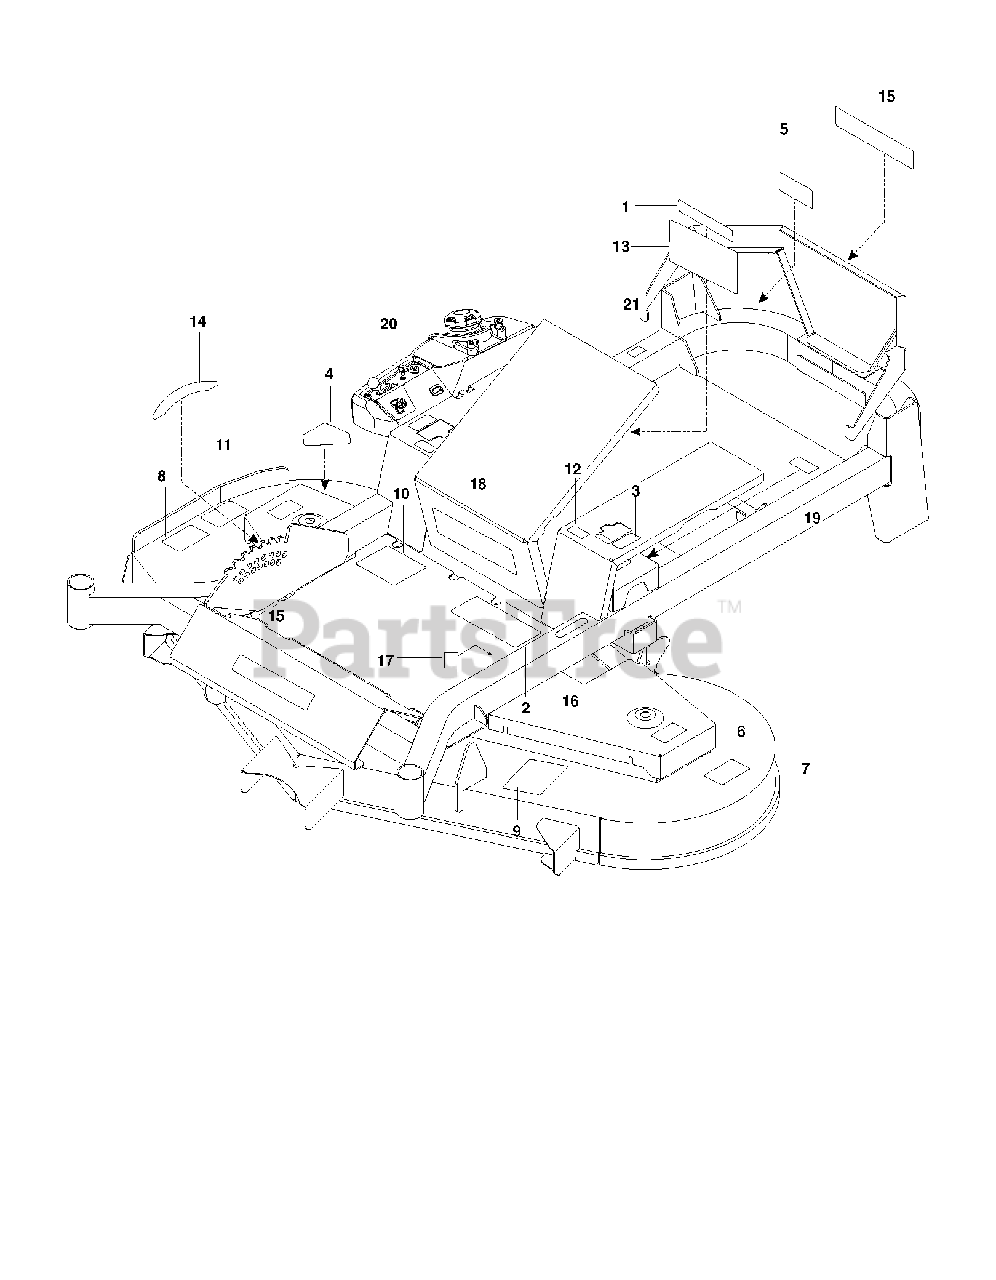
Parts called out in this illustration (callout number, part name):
2	DECAL, WARNING
3	DECAL, MOTION CONTROL
4	DECAL, CPSC
5	DECAL, BELT DRIVE
6	DECAL, NO STEP
8	DECAL, EURO SEVERING
9	DECAL, BELT ROUTING
10	DECAL, WARNING
11	DECAL, CAUTION
12	DECAL, TRACKING
13	DECAL, SERVICE
14	DECAL, HEIGHT ADJUSTMENT
16	DECAL, PARK BRAKE
19	DECAL, FUEL
21	DECAL, ECM, AUSTRALIA
